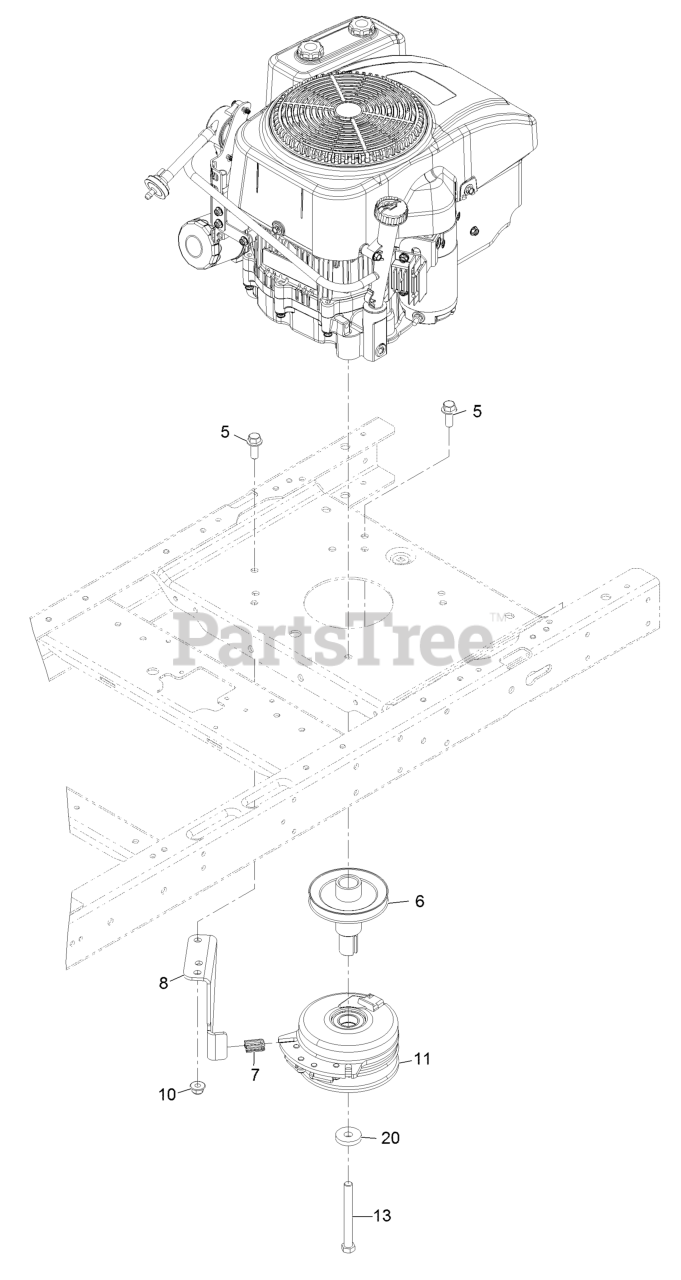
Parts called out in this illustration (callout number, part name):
5	SCREW-HHF 3/8-16 X 1
6	PULLEY-ENGINE
7	ISOLATOR-CLUTCH
8	STOP-CLUTCH
10	NUT-HF, NI
11	CLUTCH-PTO
13	SCREW-HH
20	WASHER
